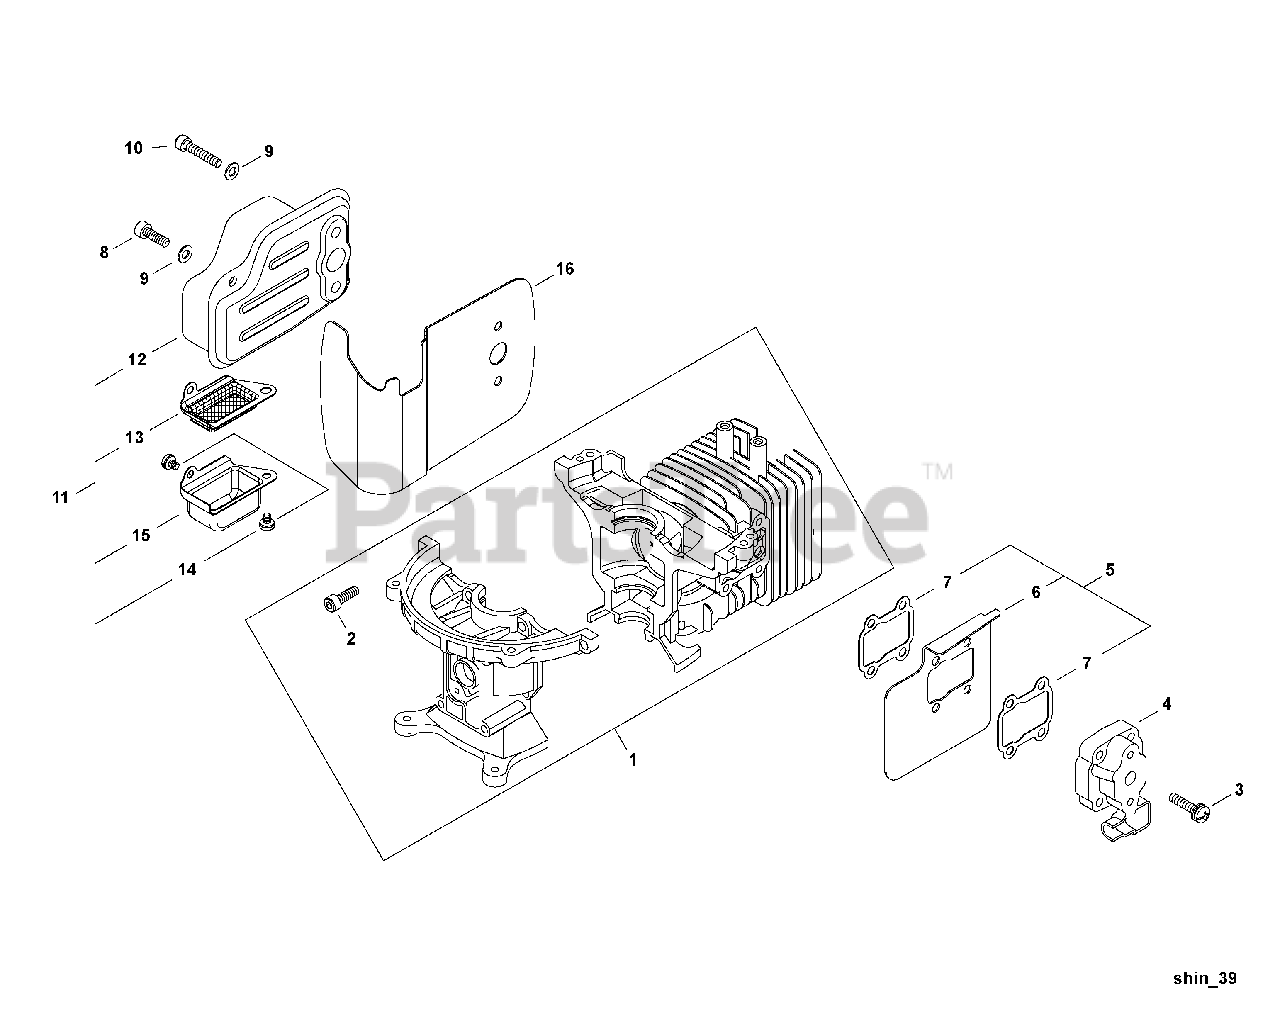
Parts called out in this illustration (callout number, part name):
1	CRANKCASE ASSY
2	SCREW - 5X16
3	SCREW - 5X22
4	INSULATOR ASSY
5	INTAKE SHIELD ASSY
6	SHIELD, INTAKE
7	GASKET, INTAKE
8	SCREW - 5X16
9	WASHER - 5
10	SCREW - 5X25
11	MUFFLER ASSY
12	MUFFLER
13	SCREEN, SPARK ARRESTOR
14	SCREW - 4X6
15	GUIDE, EXHAUST
16	SHIELD, EXHAUST
